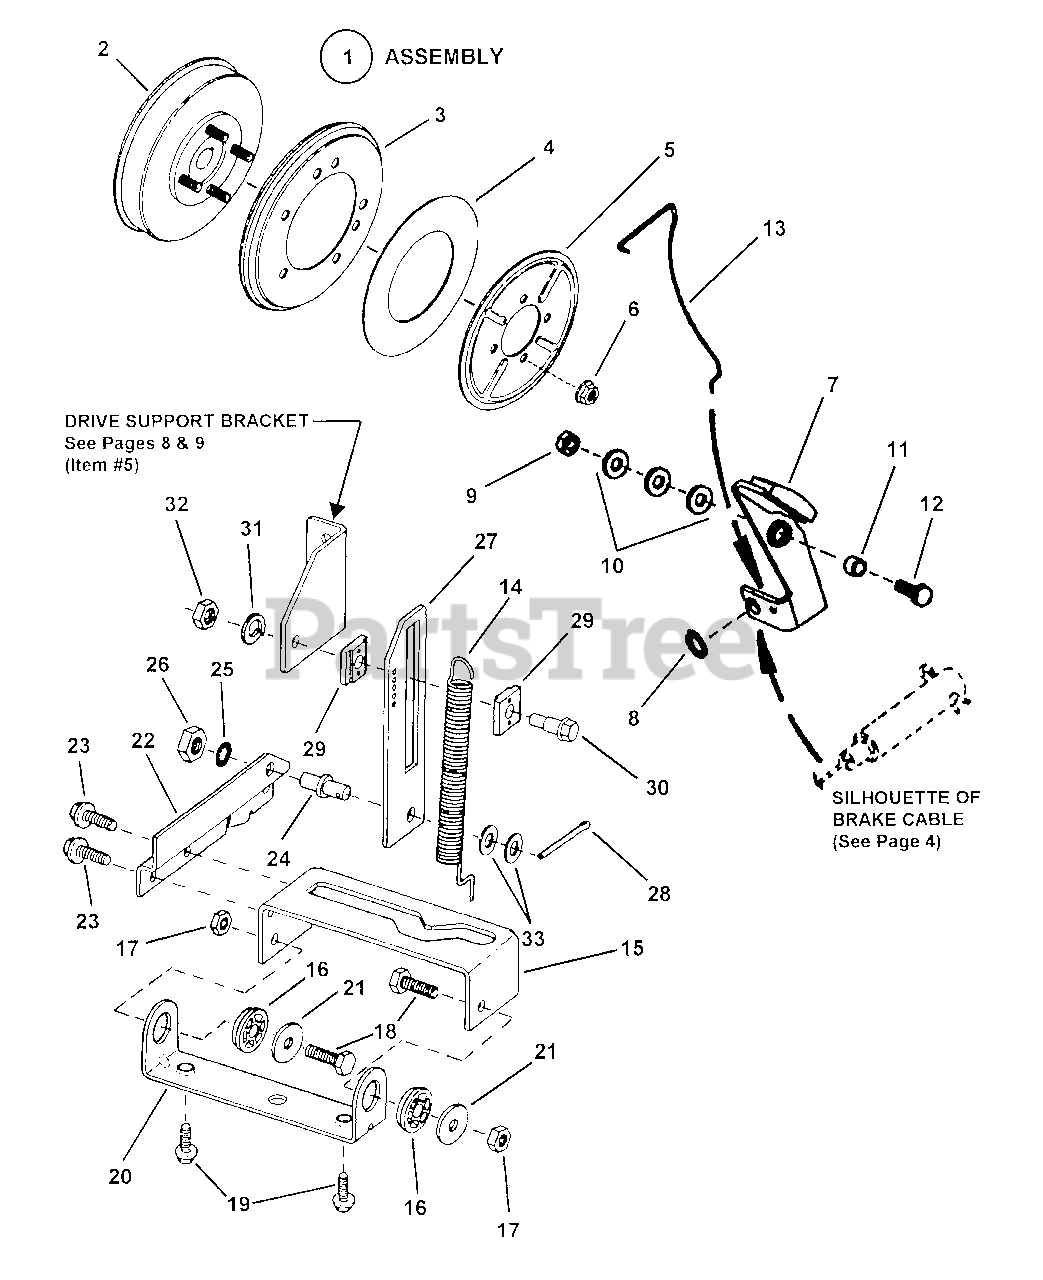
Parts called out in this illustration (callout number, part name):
1	ASSEMBLY, Smooth Clutch
2	ASSEMBLY, Driven Disc Hub
3	DISC, Driven
4	WASHER, Thrust
5	PLATE
6	NUT, 5/16-18 Hex Flange Lock
7	ASSEMBLY, Brake Lever
8	RING, 3/8" External Retaining
9	NUT, 1/4-28 Hex Top Lock
10	WASHER, 1/4 Flat
11	SPACER
12	SCREW, 1/4-28 x 1" Hex Head Cap, Grade 5
13	SPRING, Brake Return
14	SPRING, Clutch Brake
15	LIFT, Yoke
16	BEARING, Yoke
17	NUT, 5/16-24 Hex Center Lock
18	SCREW, 5/16-24 x 1" Hex Head Cap, Grade 5
19	SCREW, 3/8-16 x 5/8" Self-Tap
20	COLLAR, Yoke
21	WASHER, 5/16 Flat
22	ARM, Yoke
23	SCREW, 1/4-20 x 3/8" Self-Tap
24	STUD
25	WASHER, 3/8" Internal Tooth Lock
26	NUT, 3/8-24 Hex
27	BRACKET, Slide
28	PIN, 3/32 x 3/4" Cotter
29	SLIDE HALF
30	BOLT, 5/16-18 Shoulder
31	WASHER, 5/16" Split Lock
32	NUT, 5/16-18 Hex
33	WASHER, 3/8" SAE Flat
